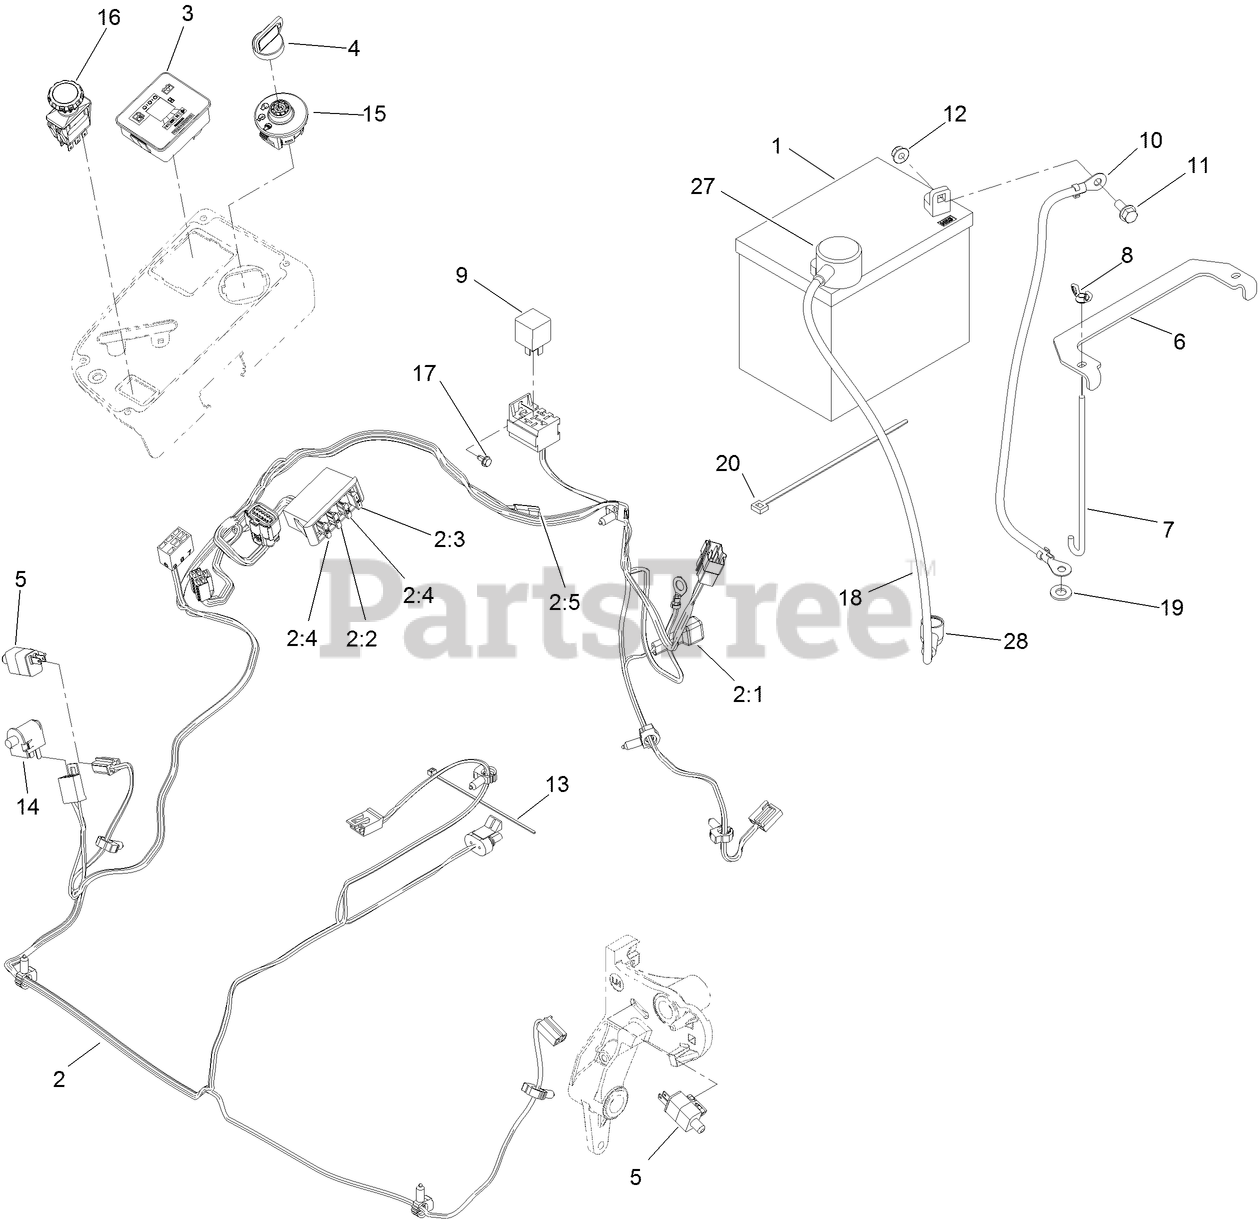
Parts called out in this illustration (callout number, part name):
1	BATTERY-DRY
2	HARNESS-WIRE, MAIN
2:2	FUSE-BLADE, 10 AMP
2:3	FUSE-BLADE, 15 AMP
2:4	FUSE-BLADE, 25 AMP
2:5	CAP-PLUG
3	FUEL/HOUR METER ASM
4	KEY-IGNITION
5	SWITCH
6	STRAP-TIE DOWN, BATTERY
7	BOLT-HOLDDOWN
8	WINGNUT
10	CABLE-BATTERY, NEGATIVE
11	SCREW-HHF
12	NUT-HF, NI
13	TIE-CABLE
14	SWITCH-BAIL
15	SWITCH-IGNITION
16	SWITCH-PTO, 10 AMP
17	SCREW-HWH
18	CABLE-BATTERY, POSITIVE
19	WASHER-FLAT
20	TIE-PLASTIC
27	INSULATOR-BATTERY
28	INSULATOR-SOLENOID
